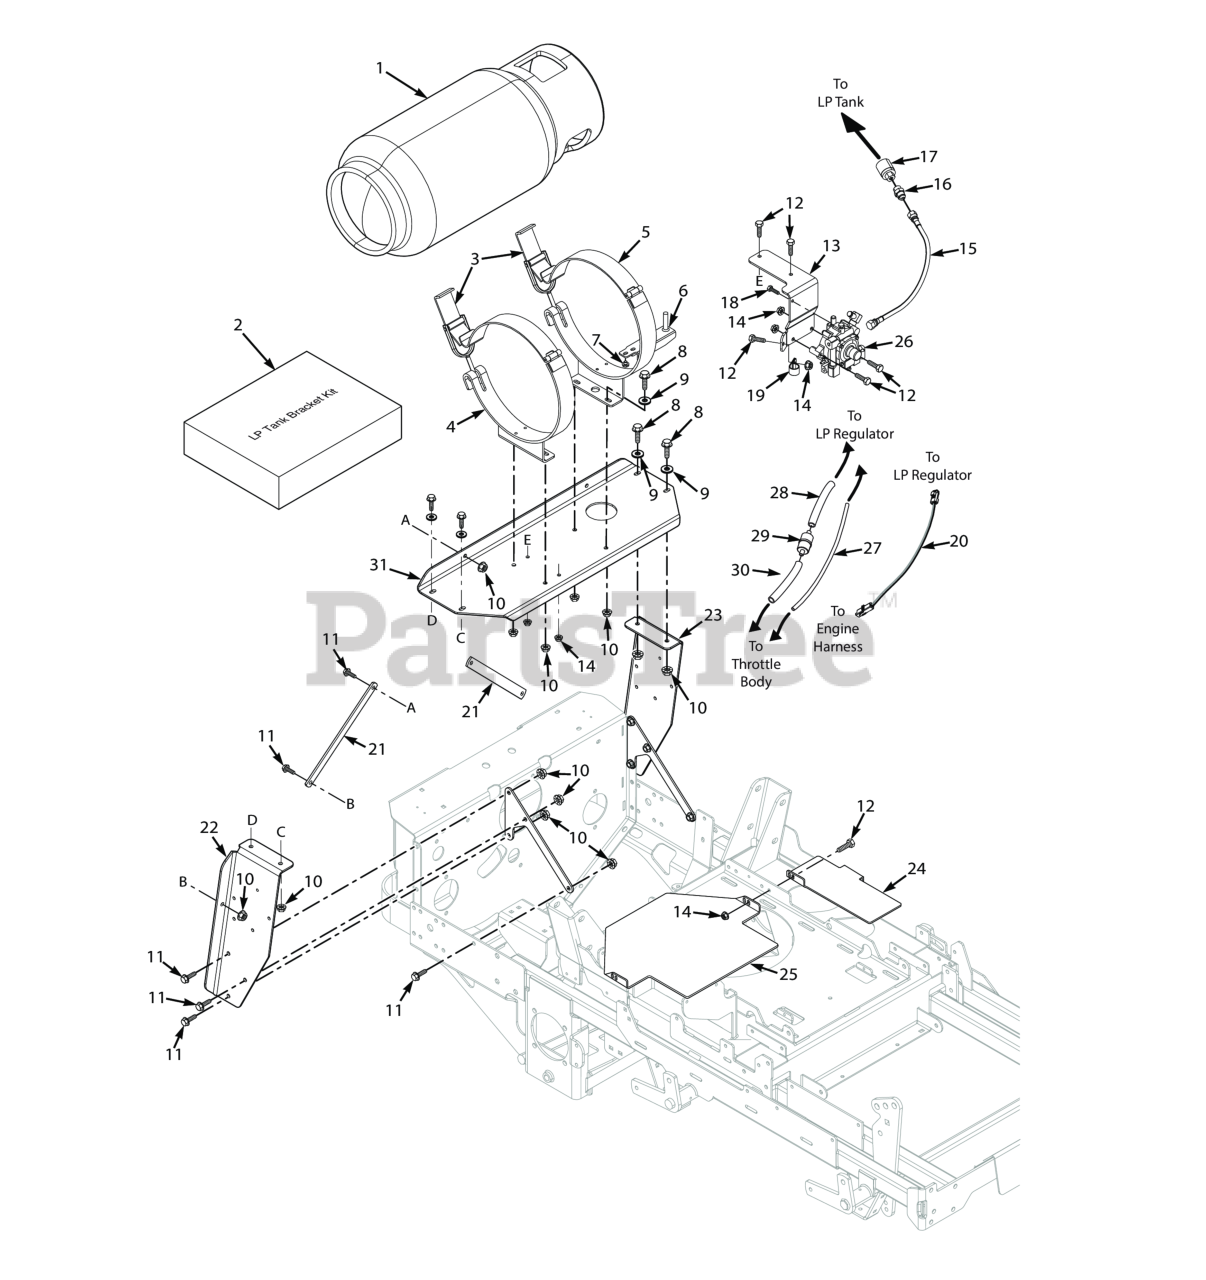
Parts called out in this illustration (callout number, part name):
1	LP Tank - Vapor
2	Mounting Bracket Kit
3	Handle, LP Tank Mounting Bracket
4	Mounting Bracket, LP Tank Rear
5	Mounting Bracket, LP Tank Front
6	LP Tank Locating Bracket
7	Bolt, Hex Head 1/2-13 x 1.5"
8	Bolt, Hex Head, 3/8-16 x 1 Gr. 5
9	Flatwasher, 3/8" Special (.391 x .938 x .105)
10	NUT, 3/8-16 SERRATED FLANGE HEX HEAD
11	Bolt, Hex Head, 3/8-16 x 3/4"
12	BOLT, SERRATED FLANGE HEX HEAD 5/16-18 X 3/4"
13	Mounting Bracket, Regulator
14	Nut, Serrated Flange 5/16-18 (Right Front Engine Mounting, Briggs and Kohler Only)
15	LP Fuel Line, 17"
16	Adapter Fitting, 9/16-18 SAE x 1/4" Pipe
17	LP Quick Coupler
18	BOLT, HEX HEAD, 1/4-20 X 3/4 GR.5
19	Clamp, Cable 3/4" ID.
20	Adapter, Wire Harness
21	Brace, Engine Mounting
22	Mounting Bracket, Tank Support - RH
23	Mounting Bracket, Tank Support - LH
24	Cover, Fuel Fill Hole
25	Cover, Fuel Tank Hole
26	LP Regulator
27	Hose
28	Hose
29	Fuel Filter
30	Hose
31	Support, LP Tank
